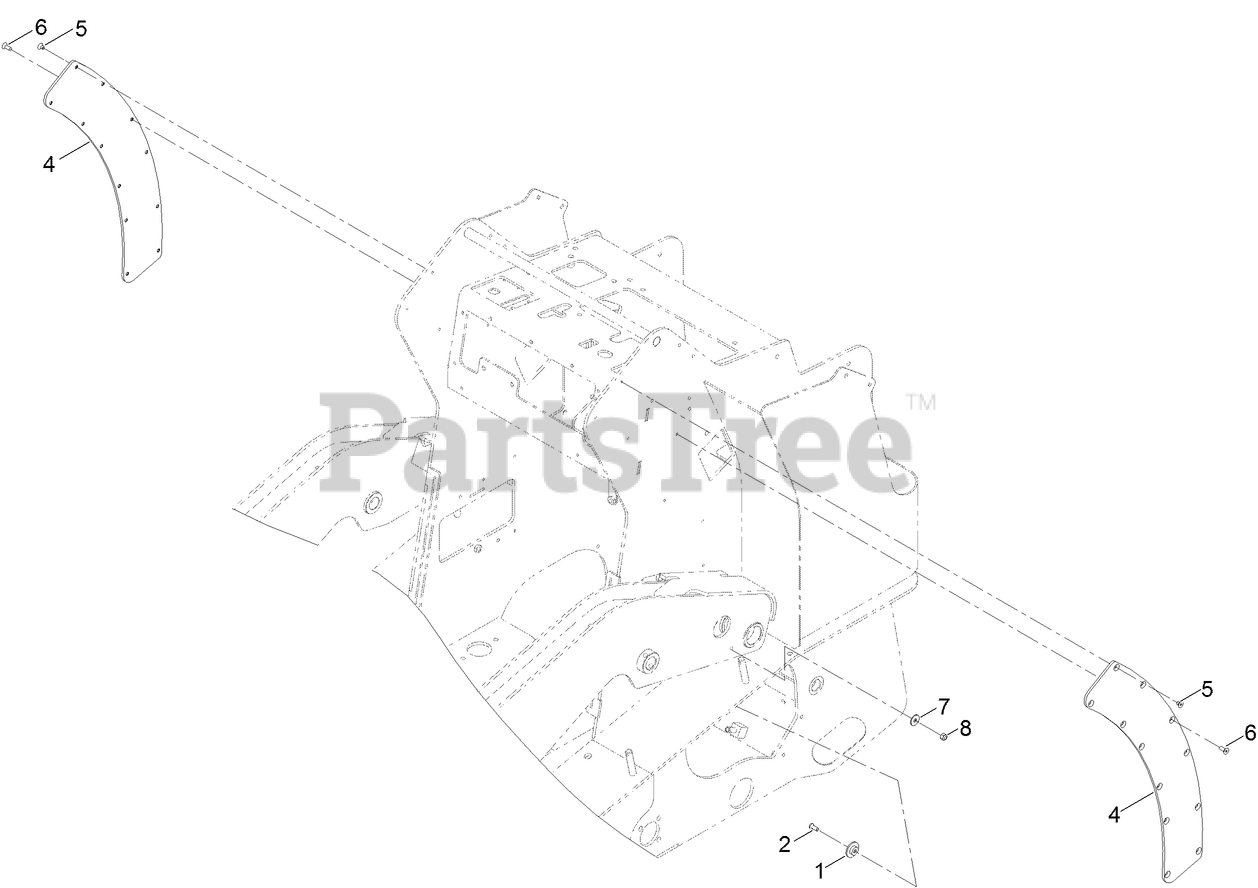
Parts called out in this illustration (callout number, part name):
2	SCREW-HSBH
4	PAD-WEAR, FRAME
5	SCREW
6	SCREW-HSFH
7	WASHER-PLAIN
8	NUT-LOCK, NI
